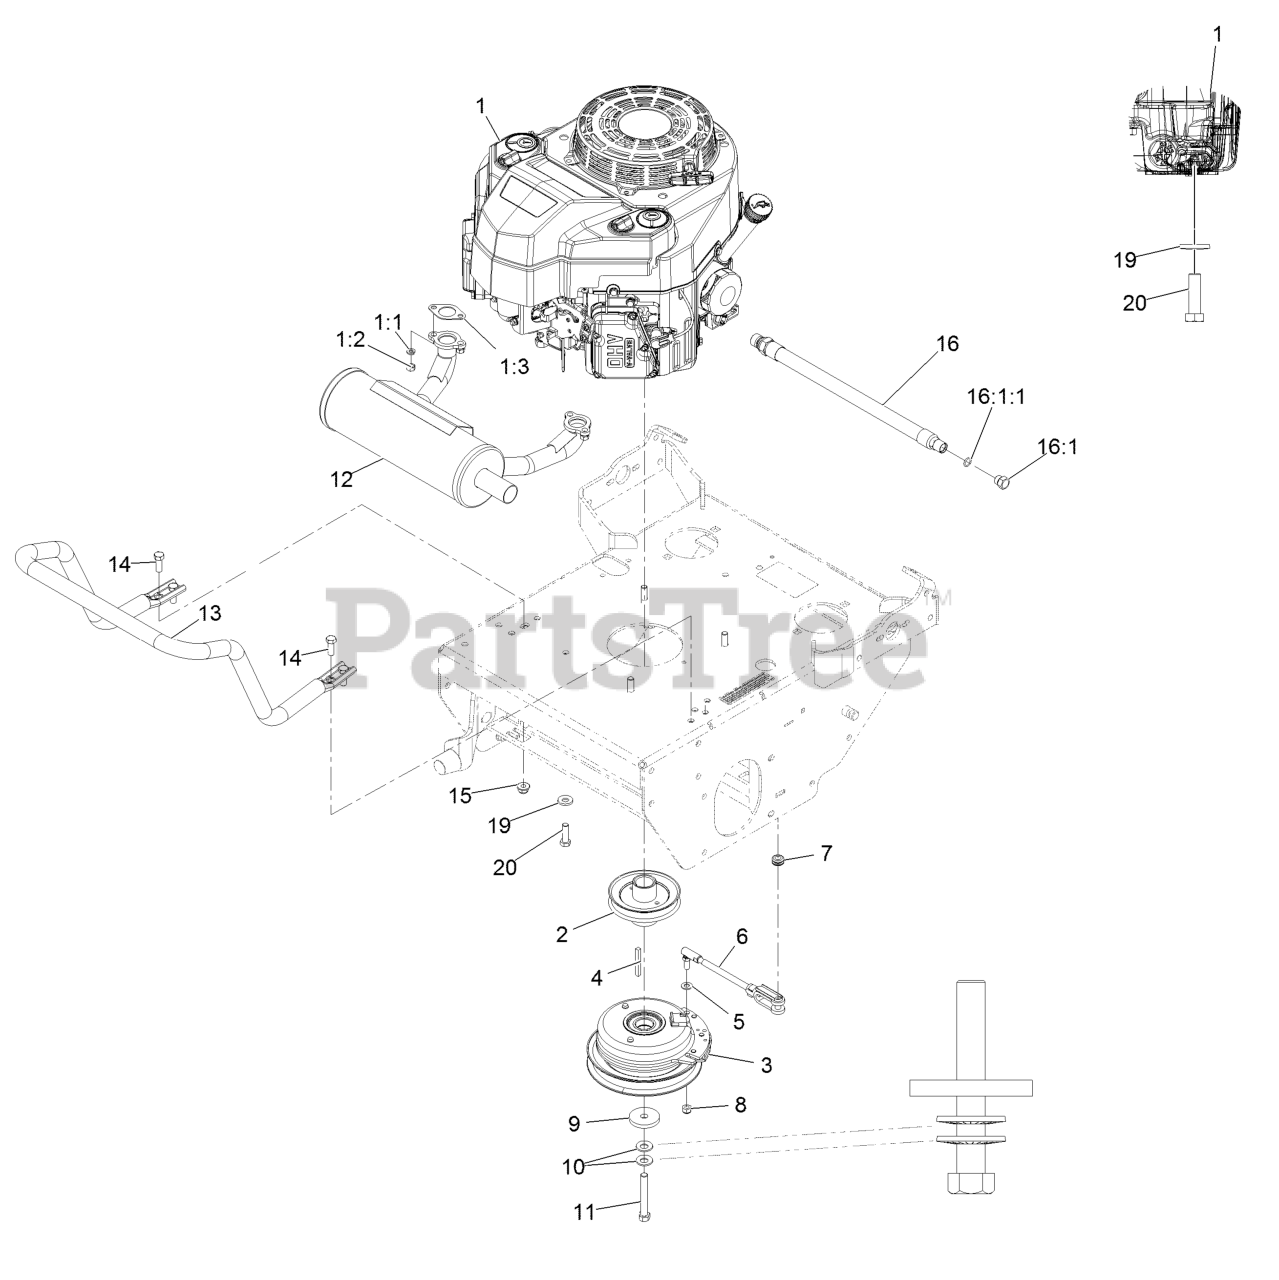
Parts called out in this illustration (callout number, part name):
1:1	Washer-Spring Lock M8
1:3	Gasket-Exhaust
2	Sheave, W/ Hub
3	Clutch, 105 Ft/Lbs, 1.13
4	Key-Machine 1/4 X 1/4 X 2
5	Washer-5/16 SAE
6	ASM, Clutch Anchor
7	Grommet
8	Nut-Lock 5/16-24
9	Washer-Clutch
10	Washer-Spring Disc 7/16
11	Screw-HH 7/16-20 X 3
12	Muffler-Horizontal
13	Guard-Muffler
14	Screw-HH 3/8-16 X 1
15	Nut-Nyloc 3/8-16 Flg
16	Asm-Oil Drain Hose W/Plug
16:1	Plug-W/O-Ring
16:1:1	O-Ring
19	Washer-Spring Disc 3/8
20	Screw-HH 3/8-16 X 1 1/4
